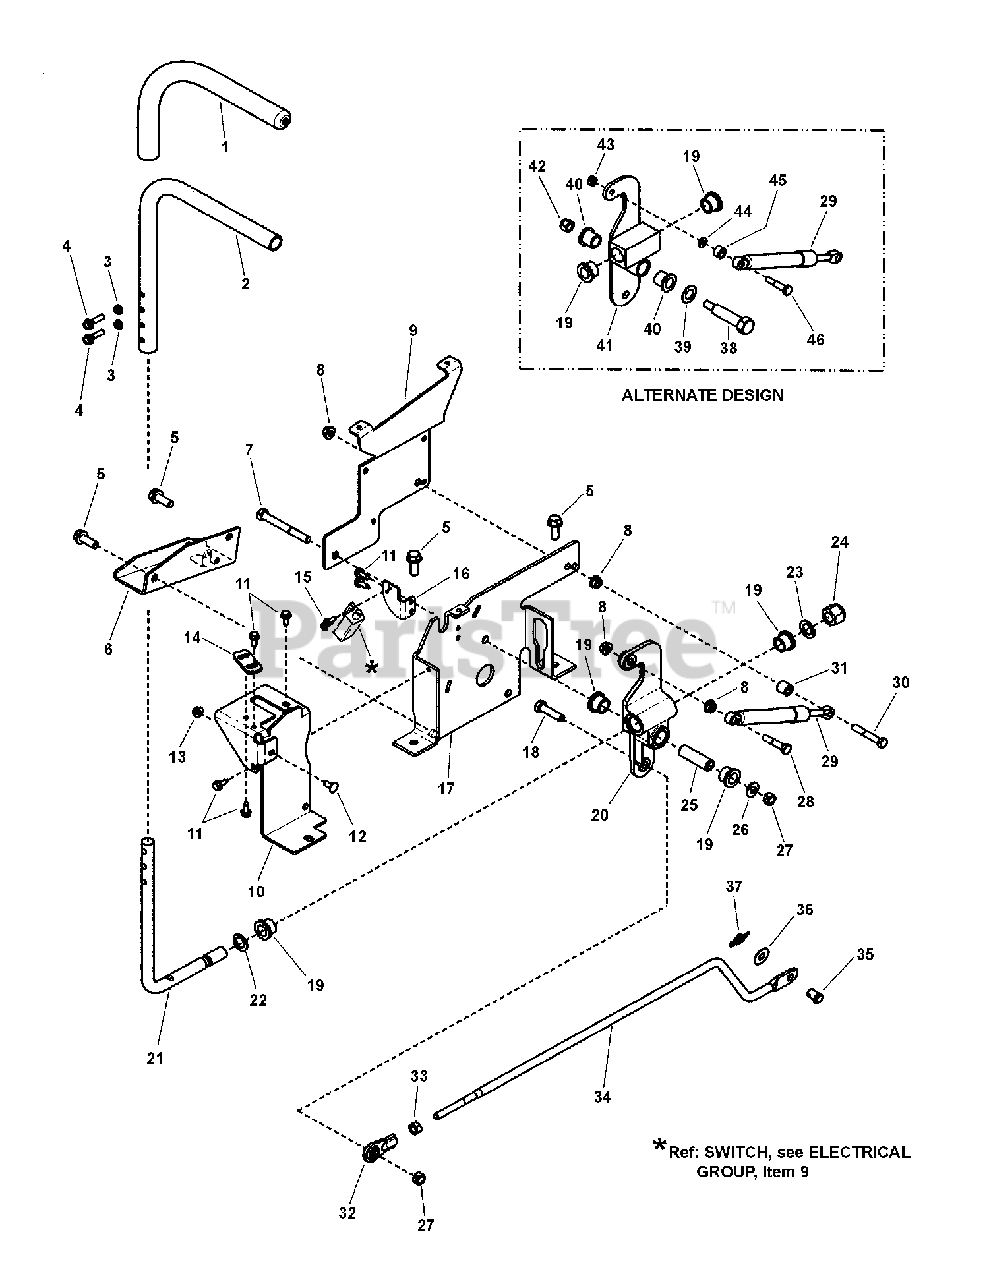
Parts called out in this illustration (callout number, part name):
1	GRIP, Handle
2	HANDLE
3	LOCKWASHER, 1/4" Spring, YZ
4	SCREW, 1/4-20 x 1" Hex Head Cap, GR 5, BZ
5	SCREW, 3/8-16 x 1" Hex Washer Self-Tap
6	BRACKET, Mount, Motor
7	SCREW, 3/8-16 x 3-1/4" Hex Head Cap, GR 5
8	NUT, 5/16-18 Hex Flange Lock, GR 5, YZ
9	BRACKET, Fender Support, RH
10	BRACKET, Guide, Stick, Control, RH
11	SCREW, 1/4-20 x 3/4" Hex Washer Self-Tap, Black
12	BOLT, 1/4-20 x 5/8" Round Head Short Square Neck, GR 5, YZ
13	NUT, 1/4-20 Hex Flange Lock, Black
14	PLATE, Foward/Reverse Adjust
15	SCREW, #10-24 x 1/2" Hex Washer Self-Tap, Torx
16	BRACKET, Switch
17	CONTROL BRACKET, RH
18	SCREW, 3/8-16 x 1-1/2 Hex Head Cap, GR 5, YZ
19	BUSHING, Bronze, 5/8 x 5/8
20	ARM, Control, Die Cast Aluminum
21	ROD, Handle
22	WASHER, .64 x .99 x .05 Flat, YZ
23	WASHER, 5/8 ID x 1.00 OD x .065 Nylon
24	NUT, 5/8-18 Hex Nyloc, YZ
25	SPACER, Sleeve, RZT
26	WASHER, 3/8" Flat (SAE)
27	NUT, 3/8-16 Hex Center Lock, YZ
28	SCREW, 5/16-18 x 1-1/2 Hex Head Cap, YZ
29	DAMPENER, Control
30	SCREW, 5/16-18 x 2" Hex Head Cap, GR 5, YZ
31	SPACER, .625 OD x .380 ID x .564 L
32	ROD END, (3/8-24 thread)
33	NUT, 3/8-24 Hex, GR B, YZ
34	ROD, Link Foward/Reverse (3/8-24 thread)
35	PIN, 7/16 x 1" Clevis
36	WASHER, 7/16" Flat
37	COTTER PIN, 1/2 Self, YZ
38	SHOULDER BOLT, 3/8-16
39	WASHER, Thrust .562 x 1.000 x .031
40	BEARING, Flange, 9/16
41	WELDMENT, Control Bracket, RH - Black
42	NUT, 3/8-16 Hex Nyloc, YZ
43	NUT, 1/4-20 Hex Center Lock
44	WASHER, 1/4" Flat, Hardened
45	SPACER, .33 x .50 x .355, Yellow
46	SHOULDER BOLT, 1/4-20 x .313 Dia.
